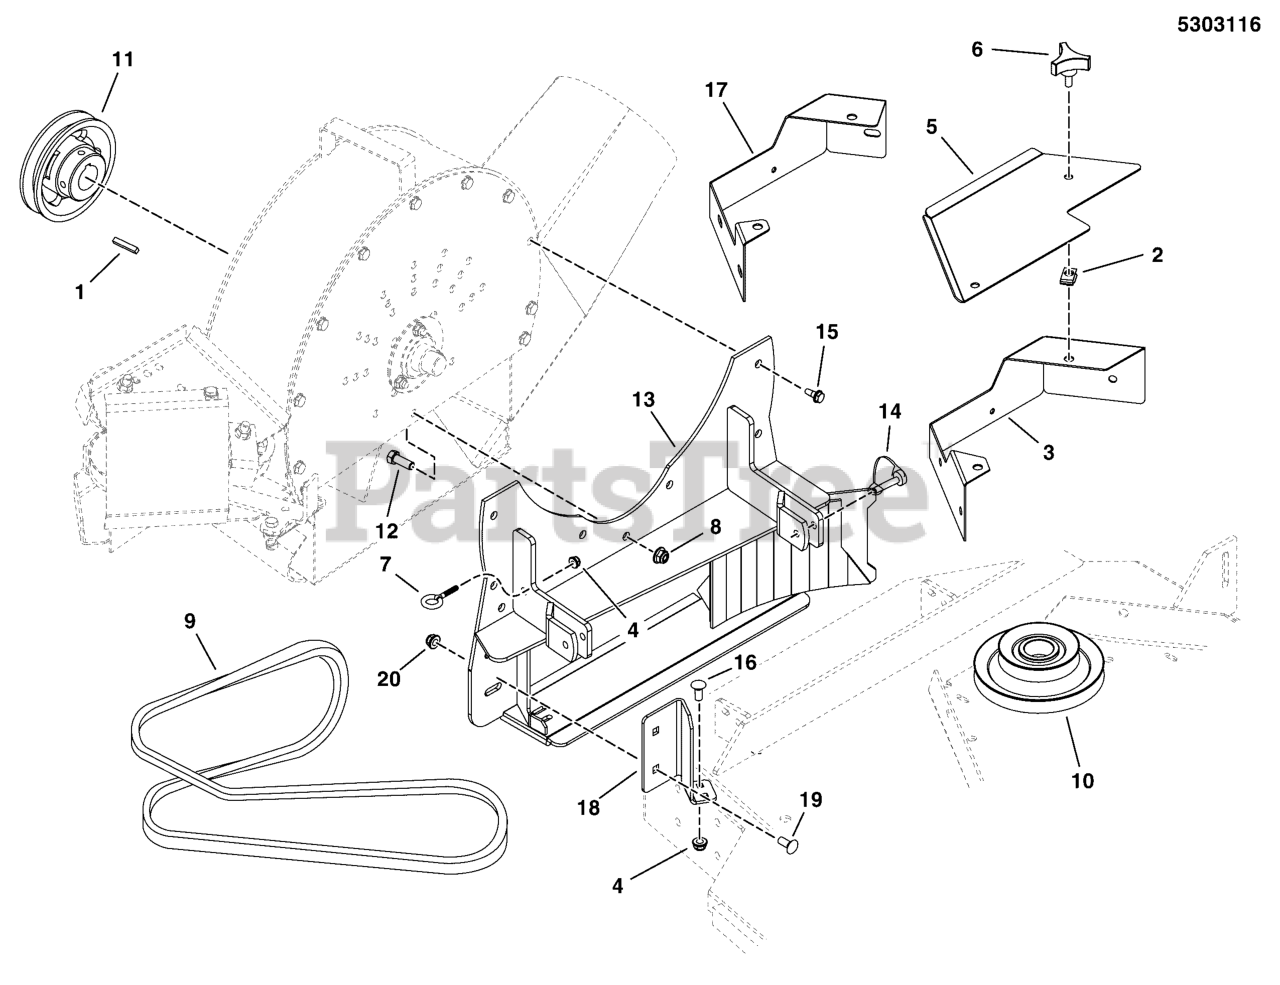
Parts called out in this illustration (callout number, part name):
1	KEY 1/4 SQ X 1 1/2 LONG
2	BODY CLIP, 5/16-18-7GA MATERIAL
3	GUARD, DECK, 61", 2000 FASTVAC - BLK
4	NUT, 1/4-20 HEX NYLOCK FLANGE
5	GUARD, BELT, 61", 2000 FASTVAC - BLK
6	KNOB, PLASTIC, 5/16-18 X 3/4
7	EYE BOLT, 1/4-20 X 2.5, 1THRD, .5EYE,CZ
8	NUT, 3/8-16 HEX NYLOCK FLANGE
9	BELT, 96" EL, A-SECT, ARAMID, WRAPPED
10	PULLEY,DECK,61 BLOWER UNIT
11	PULLEY, BLOWER AXLE, 61
12	BOLT, 3/8-16 X 1" GD5 CZ
13	PACKAGE, 61" ADAPTER ASSY (2011)
14	SNAPPERPIN, 5/16 X 2
15	BOLT, 5/16-18 X 5/8" Self Lock
16	BOLT-RD HD SH SQ NK 1/4-20X0. 625 G5 BLK
17	GUARD, DECK, 61/200XT, FASTVAC - BLK
18	BRACKET, DEFLECTOR PLATE, 61" iCD - BLK
19	BOLT, 5/16-18 X 3/4, CARRIAGE
20	NUT, 5/16-18 HEX NYLOCK FLANGE
